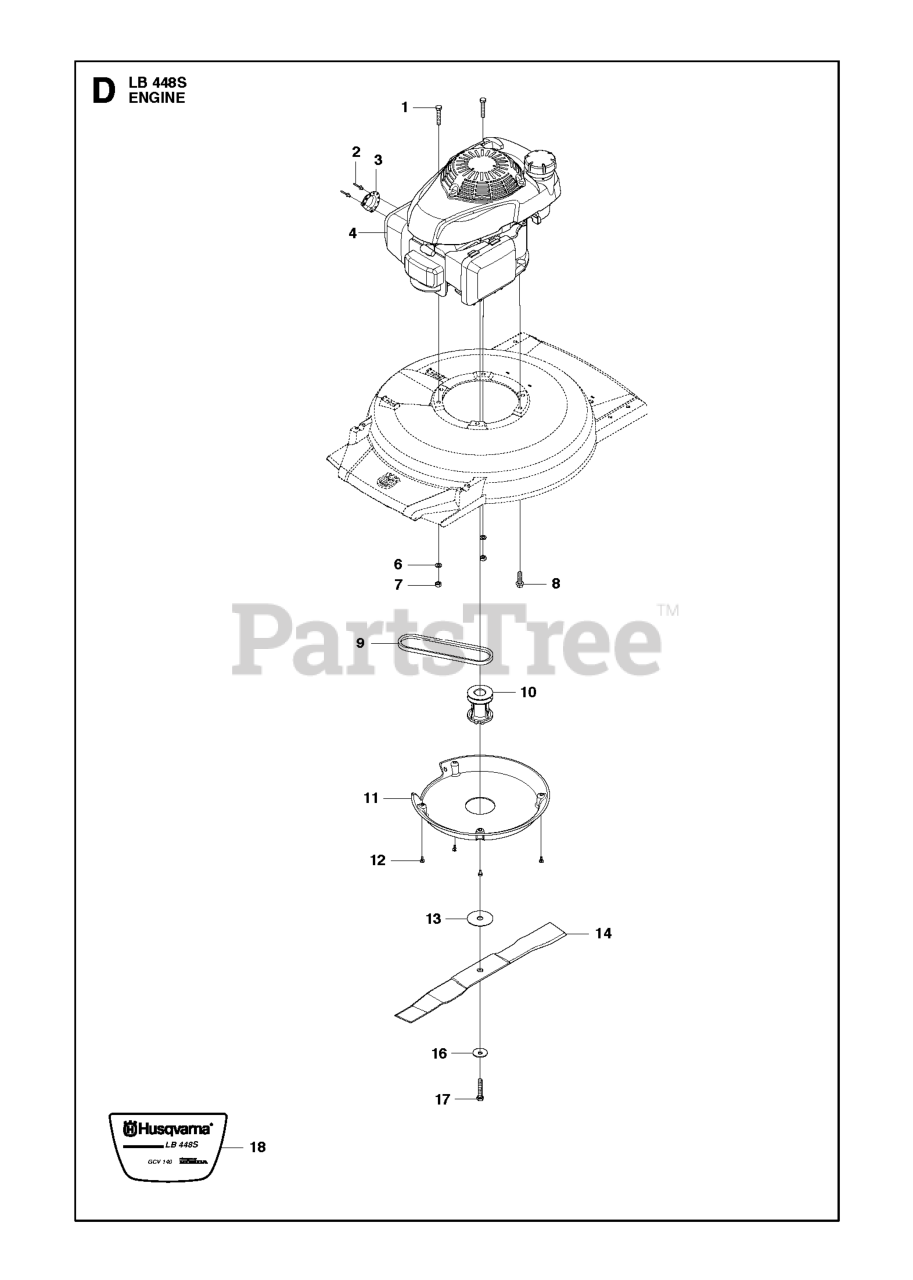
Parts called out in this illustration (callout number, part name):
6	WASHER BRB 8.4X17
7	LOCKNUT M8
12	SCREW ITXPANTT M5X10 ZPB (A00
